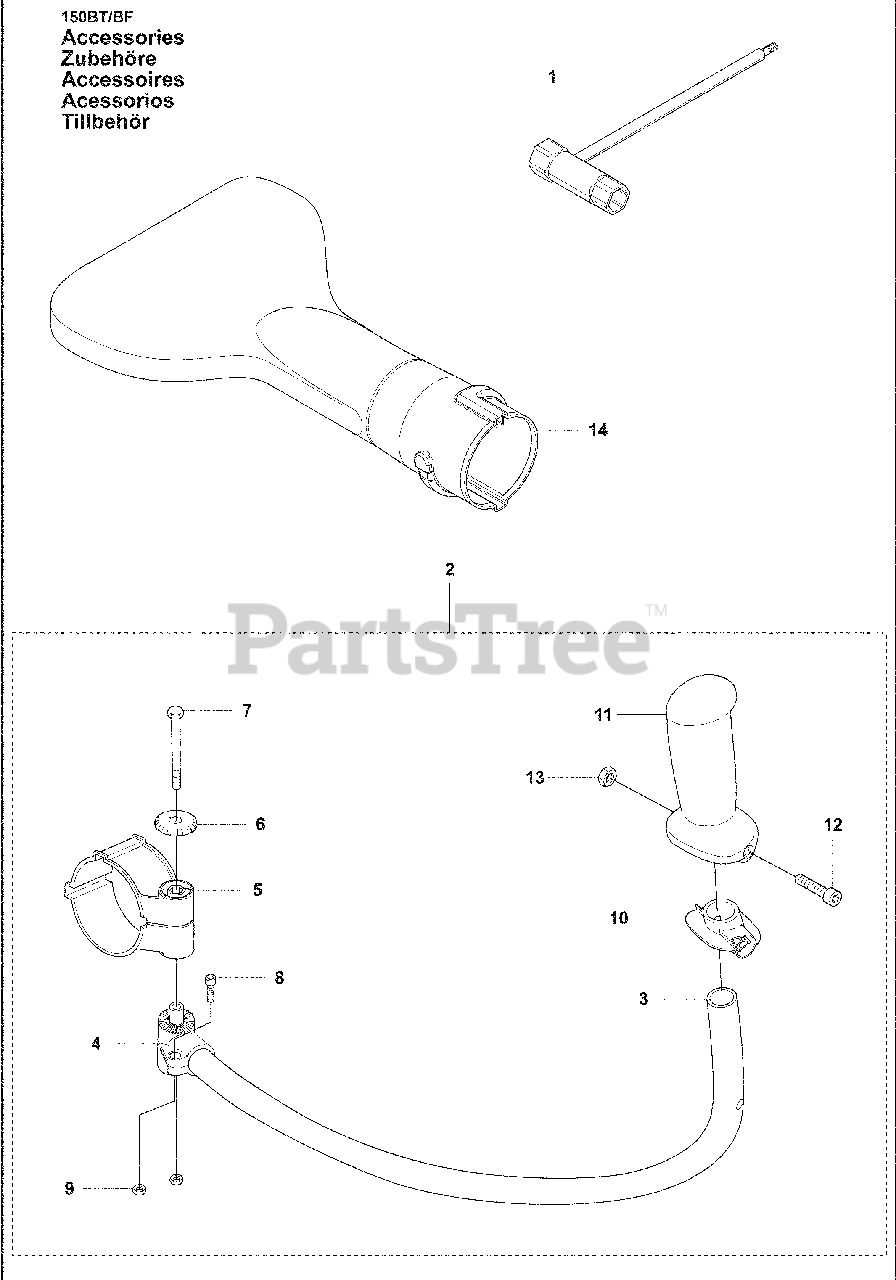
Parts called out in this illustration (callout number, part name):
1	SOCKET
2	Handlebar Assembly
5	Holder, TH
6	Air Filter Cover Knob
8	Screw, MC6S 5 X 10
9	Hex Nut, M5 X .80 DIN
13	Hex Nut, M5 X .80 DIN
14	Flat Nozzle
